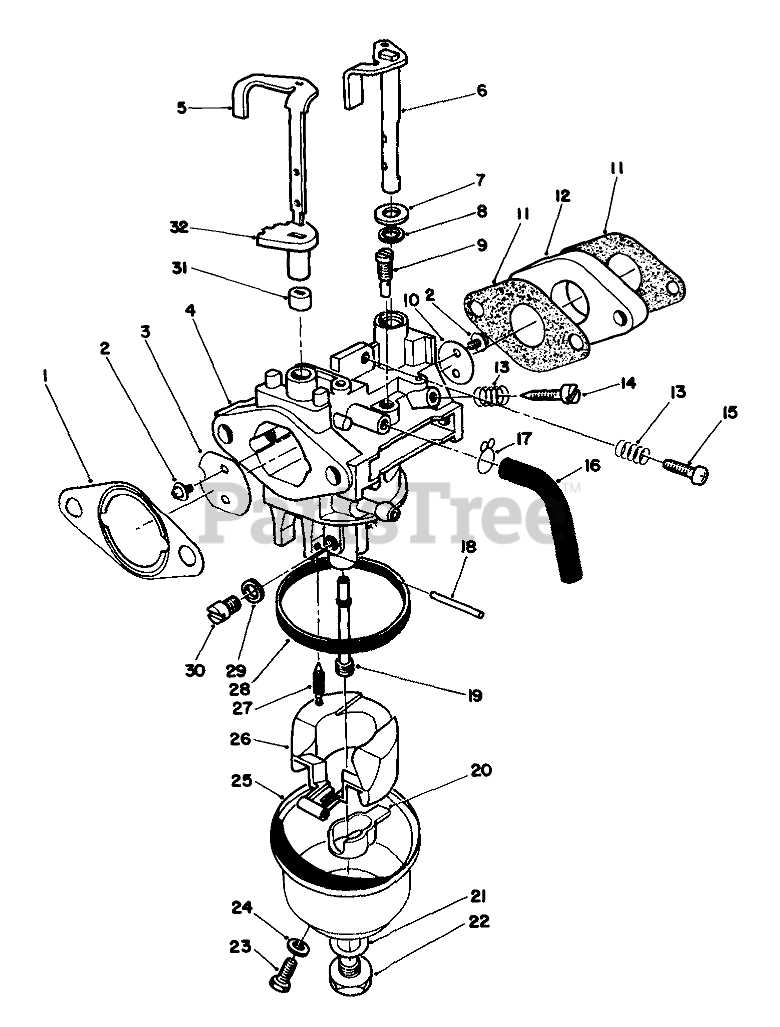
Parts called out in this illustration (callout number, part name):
1	GASKET F/W ENGINE
2	Screw
3	VALVE
4	Body-Carburetor
5	Shaft-Choke Valve
6	SHAFT
7	WASHER
8	Seal-Throttle Shaft
9	JET - PILOT
10	VALVE
11	GASKET INTAKE
12	INSULATOR - CARB.
13	SPRING-PILOT SCREW
14	ADJUSTER
15	SCREW
17	CLAMP
18	Pin
19	NOZZLE - MAIN
20	SPACER
21	GASKET
22	SCREW
23	SCREW
24	GASKET
26	FLOAT
27	NEEDLE
28	FLOAT BOWL GASKET
29	SPACER
30	JET - MAIN
31	LOWER CHOKE RING
32	UPPER CHOKE RING
